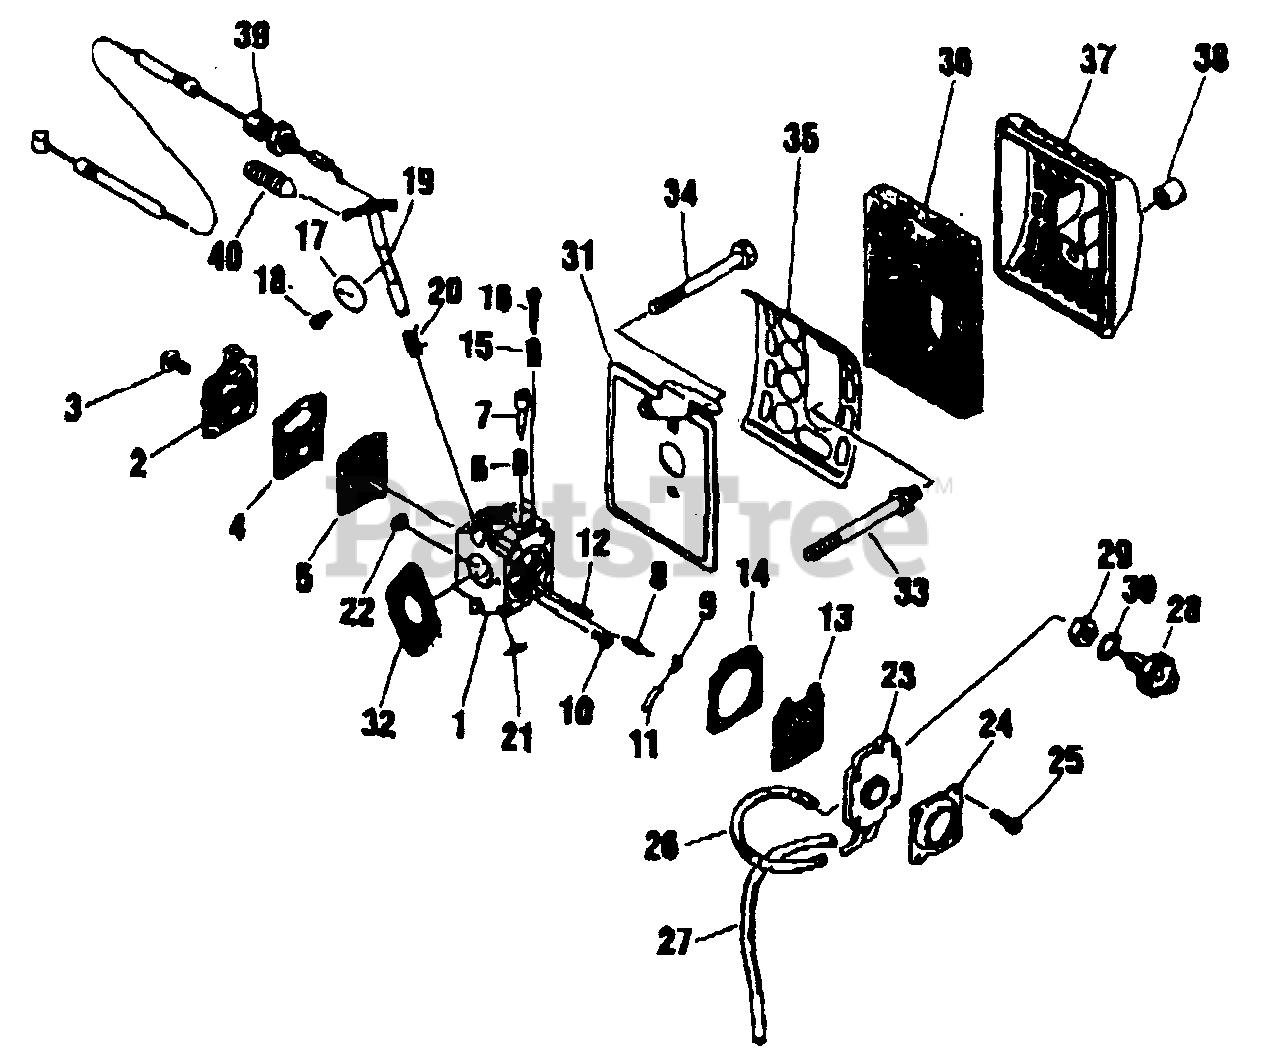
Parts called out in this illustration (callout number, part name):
1	BODY, CARBURETOR
2	COVER, PUMP
3	SCREW, PUMP COVER
4	GASKET, PUMP
5	DIAPHRAGM, PUMP
6	SPRING
7	NEEDLE - LOW SPEED
8	VALVE, INLET NEEDLE
9	LEVER, METERING
10	SCREW, METERING LEVER PIN
10	SCREW
11	PIN, METERING LEVER
11	PIN
12	SPRING, METERING LEVER
12	SPRING
13	DIAPHRAGM, METERING
14	GASKET, METERING
15	SPRING
16	NEEDLE - HIGH SPEED
17	VALVE, THROTTLE
18	SCREW
19	SHAFT
20	SPRING
21	RING, RETAINING
22	STRAINER
23	STARTER BODY
24	RETAINER, PURGE BULB
26	PIPE, PURGE
27	TUBE, DRAIN
28	PRIMING PUMP
29	NUT
30	LOCKWASHER
31	CHOKE ASSY
32	GASKET, INTAKE
34	BOLT - 5X50
35	PLATE, AIR CLEANER
36	FILTER, AIR
37	COVER, AIR FILTER
38	NUT
39	CABLE, THROTTLE
40	SPRING
